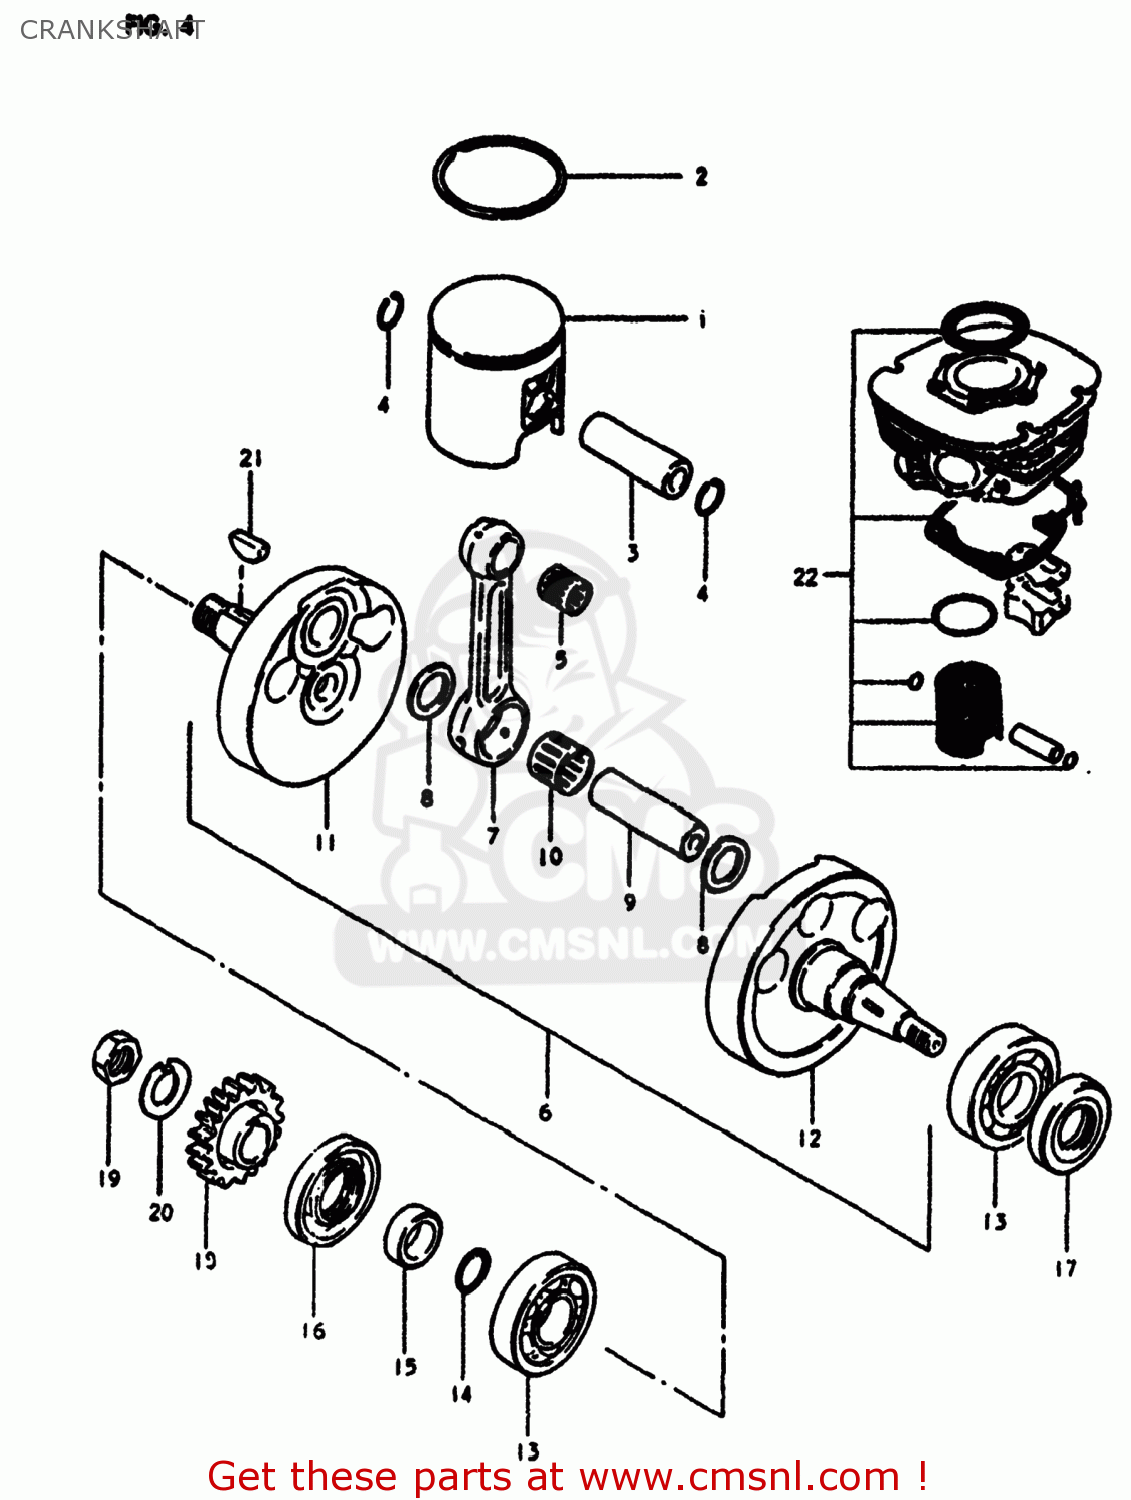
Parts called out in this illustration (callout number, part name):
1	PISTON
2	RING,PISTON
3	PIN,PISTON (18MM)
4	CIRCLIP
5	BEARING(18X23X22)
6	CRANKSHAFT ASSEMBLY
7	ROD,CONNECTING
8	WASHER(24X29X2)
9	PIN,CRANK
10	ROLLER BEARING (24X30X1
11	CRANKSHAFT
12	CRANKSHAFT,LEFT
13	BEARING
14	O RING(D:2.4,ID:19.8)
15	SPACER
16	SEAL,OIL(32X52X8.4)
17	SEAL,OIL(24X50X9)
18	GEAR,PRIMARY DRIVE
19	NUT
20	WASHER
21	KEY
22	PISTON SET
